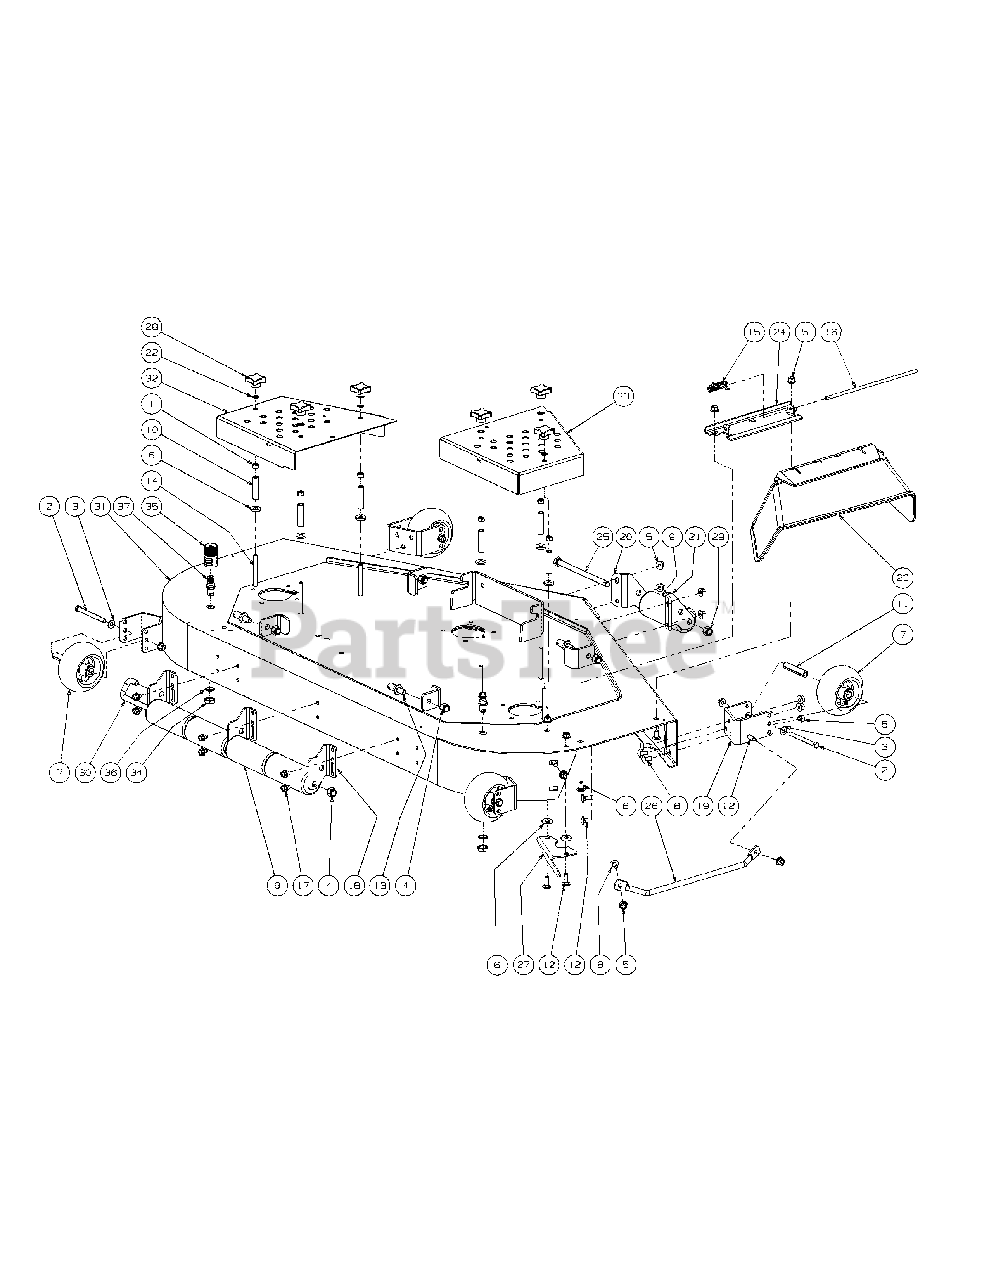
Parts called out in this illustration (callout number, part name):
1	Hex Nut 3/8-16
2	Hex Cap Screw, 3/8-16, 3.75
3	Flat Washer, 3/8
4	Lock Nut, Nylon Insert, 1/2-13
5	Flange Lock Hex Nut, 3/8-16
6	Idler Washer
7	Complete Wheel, 5.00 Dia.
8	Carriage Bolt, 3/8-16 x .75 Lg.
9	Front Roller
10	Spacer Stop Deck
11	Wheel Spacer
12	Carriage Bolt, 3/8-16 x 1
13	Pin, 5/8 Dia. x 1.2 Lg.
14	Carriage Bolt, 3/8-16 x 3.50
15	Torsion Spring, 0.4ID x 2.16Lg
16	Chute Deflector Rod
17	Hex Index Washer Screw, 3/8-16, .5
22	External Washer, 3/8
23	Chute Deflector
24	Chute Deflector Bracket
25	Hex Cap Screw, 1/2-20 x 7.50
26	Finger Guard
28	Plastic Knob
29	Lock Nut, Nylon Insert, 1/2-20
30	J-Hook w/ Threaded Roller
31	60 Fabricated Deck Assembly
32	Belt Cover, LH
33	Belt Cover, RH
34	Hex Nut, M16-1.5
35	Water Nozzle Adaptor
36	Lock Washer, 17 x 23.8 x 1.95
37	Deck Water Nozzle
